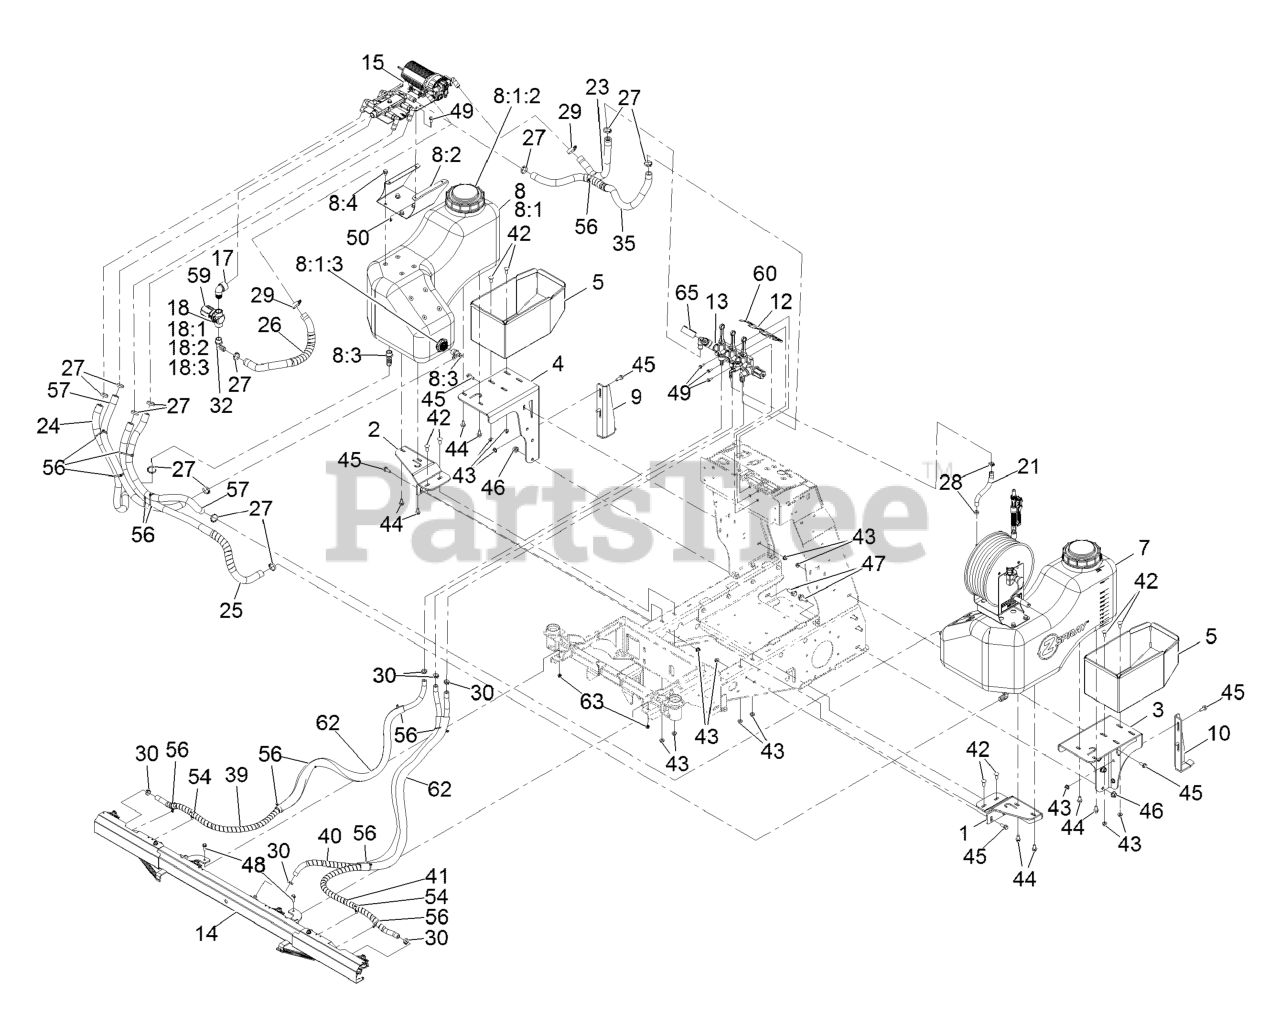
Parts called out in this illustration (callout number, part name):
1	Mount-Tank, LH Wing
2	Mount-Tank, RH Wing
3	Mount-Box, Lt Fert
4	Mount-Box, Rt Fert
5	BOX-FERT
7	ASM-Tank, Hose Reel
8	ASM-Tank, Rt
8:1	ASM-TANK, RT
8:1:2	CAP-TANK, SPRAY
8:1:3	FITTING-BULKHEAD
8:2	FITTING-ELBOW, 90
8:3	PLATFORM, LIQUID VALVE MO
8:4	Screw-HHF
9	Bracket-Anti-Tip, Rt
10	Bracket-Anti-Tip, Lt
12	Bracket-Manifold
13	ASM-Manifold
14	ASM-Boom, Spray
15	ASM, Liquid Valve
17	ELBOW-90DEG
18	STRAINER-INLINE
18:1	BOWL-STRAINER
18:2	GASKET-HEAD, LINE STRAINE
18:3	Screen-Strainer, 50 Mesh
21	Hose-Spray
23	Hose-Spray
24	Hose-Spray
25	Hose-Spray, Wrapped
26	Hose-Spray, Wrapped
27	Clamp-Oetiker, 167
28	CLAMP-OETIKER, 167
29	CLAMP-HOSE
30	CLAMP-OETIKER, 167
32	FITTING-ELBOW, 90
35	Hose-Spray, Wrapped
39	Hose-Spray, Wrapped
40	Hose-Spray, Wrapped
41	Hose-Spray, Wrapped
42	SCREW-CARR
43	Nut-Hex Flange
44	SCREW-HHF
45	SCREW-HHF
46	NUT-HEX FLANGE
47	SCREW-HHF
48	SCREW-HHF
49	Screw-HHF
50	Nut-Hex Flange
54	CLIP-TIE
56	TIE-CABLE
57	Hose-Spray
59	DECAL-CAP, STRAINER
60	Decal-Valve, Boom
62	Guard-Mesh
63	Nut-Hex Flange
65	GAUGE
